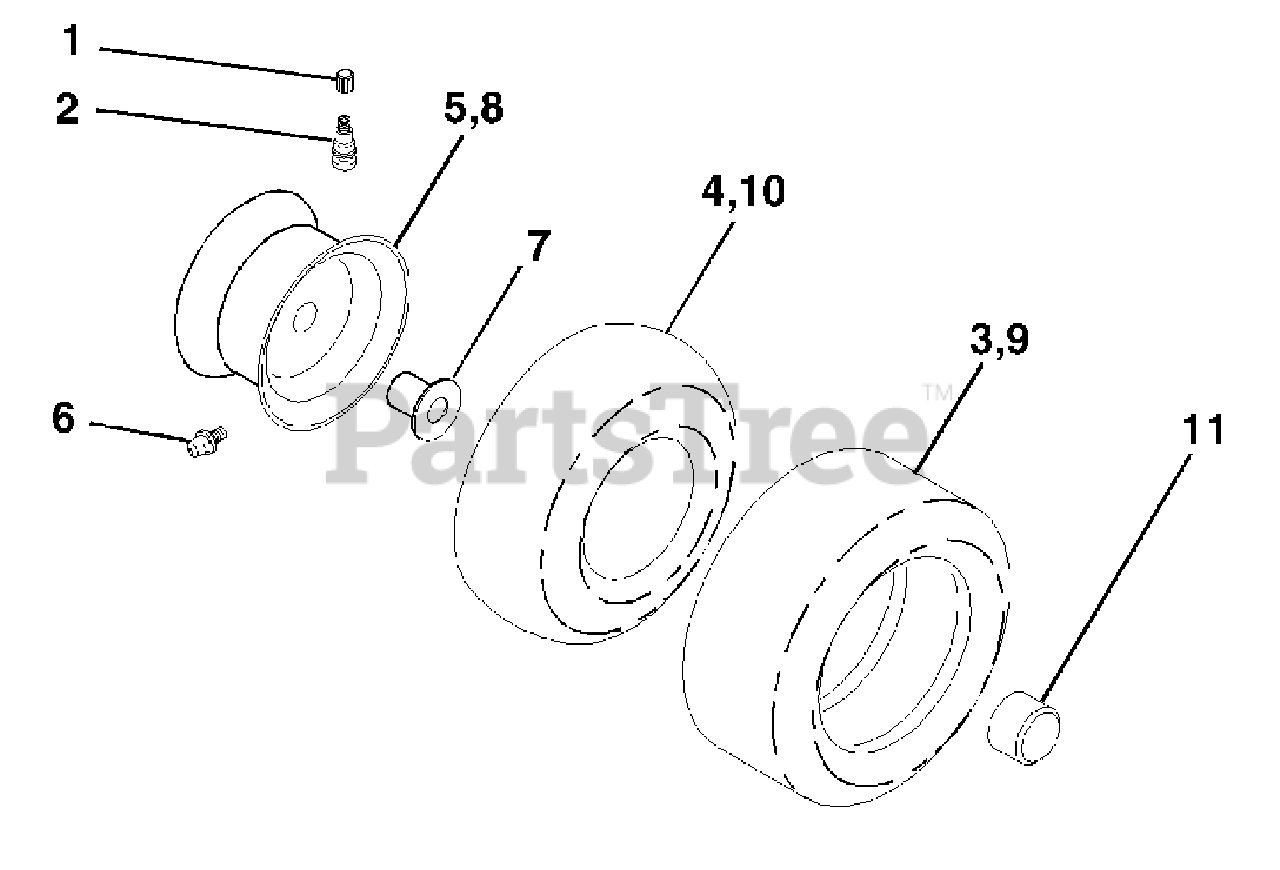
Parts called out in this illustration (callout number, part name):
1	Cap Valve Tire
2	Stem Valve
3	Tire F T 15 X 6 0 - 6 Service
4	Tube Front
5	Rim Asm 6" front Service
6	Fitting Grease
7	Bearing Flange
8	Rim Asm 8" rear Service
9	Tire R T 20 x 10-8 Service
10	Tube Rear
11	Cap Axle Blk 1 50 X 1 00
